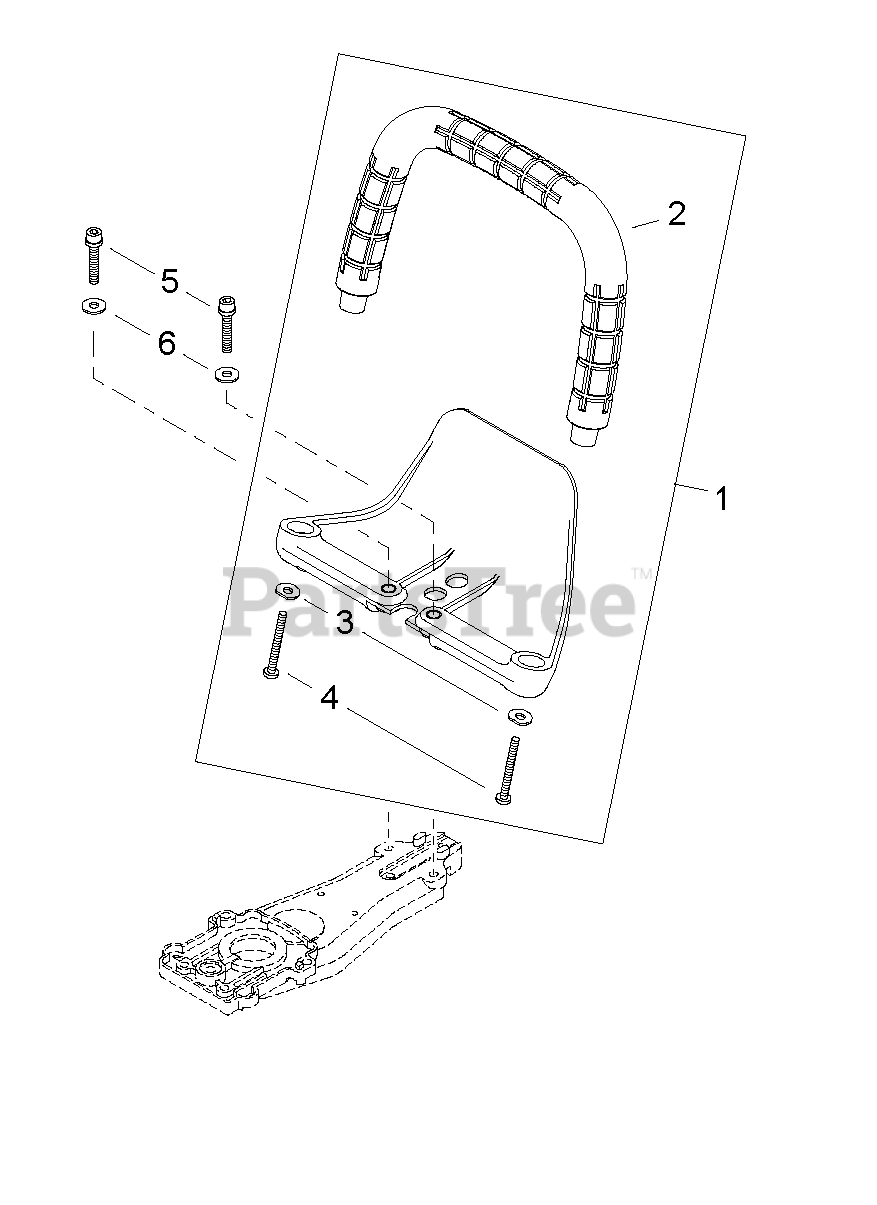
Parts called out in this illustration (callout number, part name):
1	HANDLE ASSY - FRONT
2	HANDLE - FRONT
4	SCREW - 5 -- TAPPING
5	SCREW - 6X35
